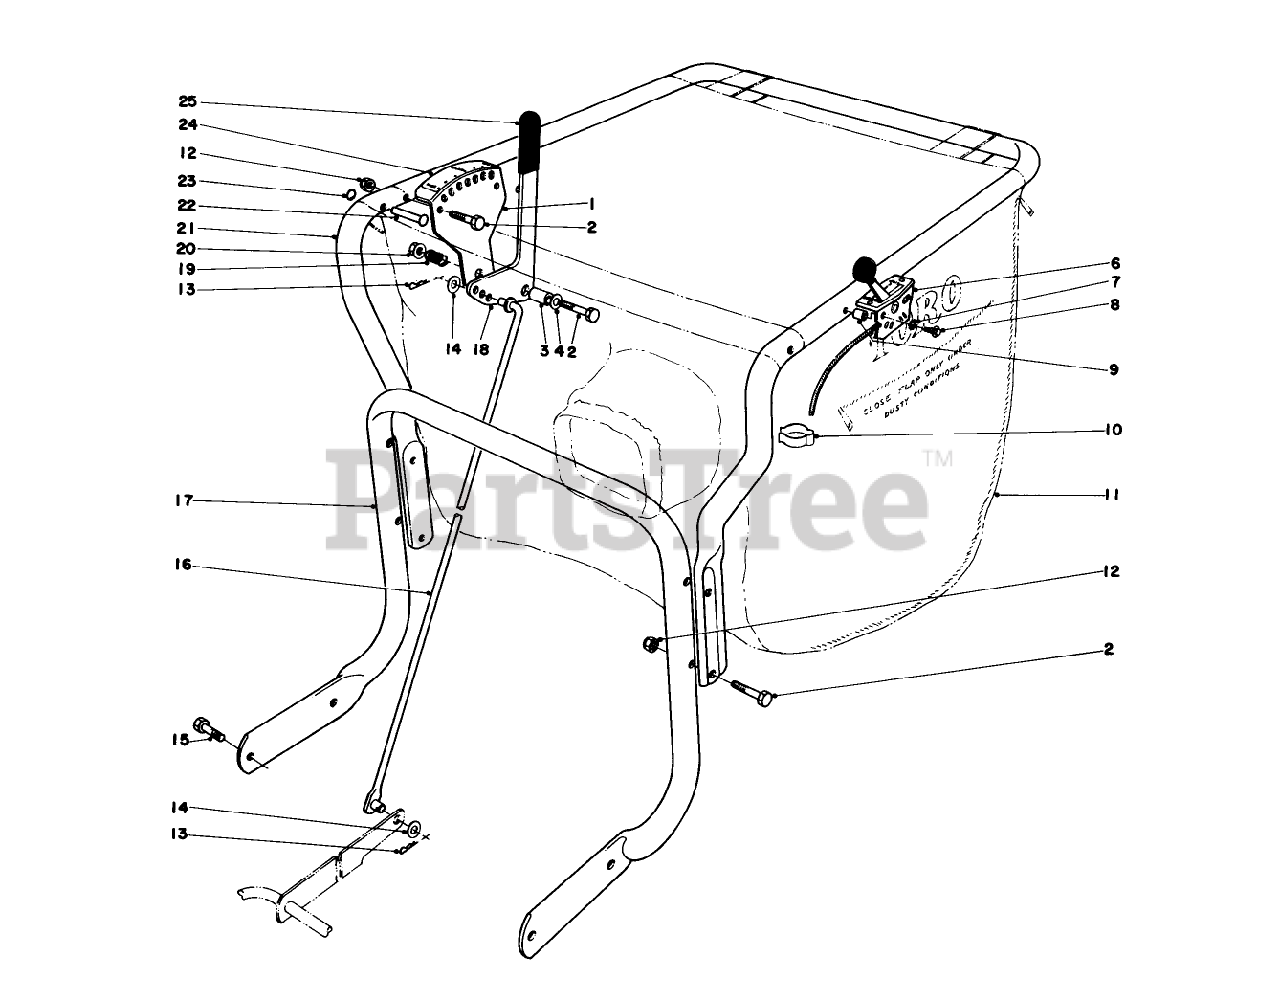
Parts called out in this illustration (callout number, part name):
2	SCREW-HH
3	SPACER
4	WASHER-FLAT
7	WASHER-LOCK, EXT
9	SPACER
12	NUT-LOCK, CONE
13	PIN-COTTER
14	WASHER-FLAT
15	Screw
17	HANDLE
19	SPRING-COMPRESSION
20	NUT-HF
21	HANDLE-UPPER, VACUUM
22	RIVET
23	RING-GRIP
25	GRIP-HANDLE
